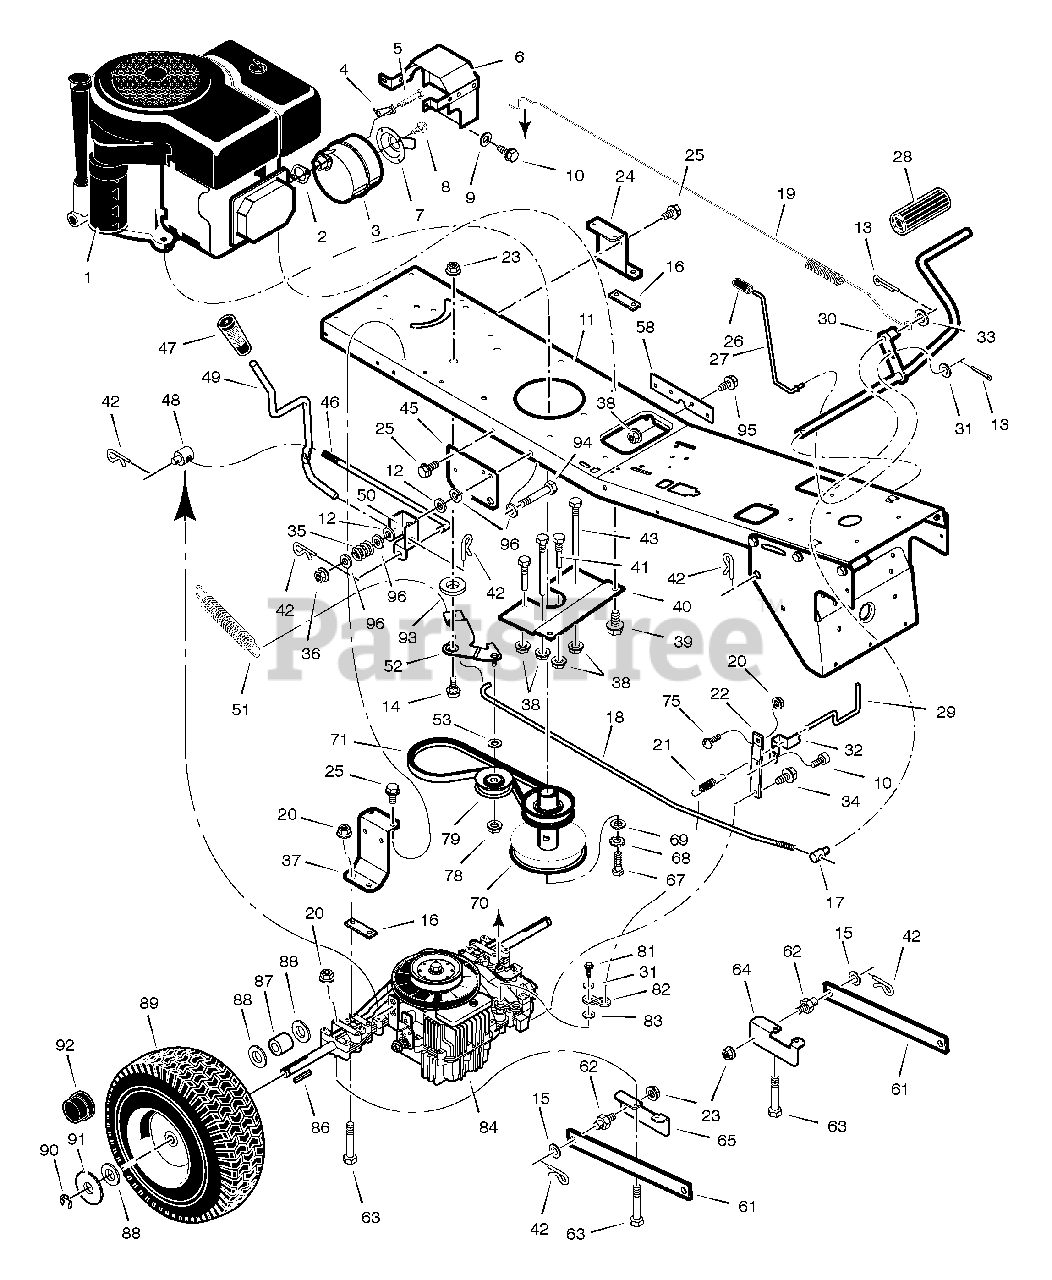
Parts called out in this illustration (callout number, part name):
1	Engine
2	GASKET, Exhaust
3	Muffler
4	Lock, Muffler Screw
5	Bolt, Hex
6	Shield, Heat
7	Tube, Exhaust
9	Washer, Lock
10	Screw
13	Pin, Cotter
14	Bolt, Shoulder
16	Plate, Transaxle
17	Nut, Adjusting
18	Rod, Clutch Hydro
19	Spring, Brake
20	Nut
21	Spring, Roll Release
22	Bracket, Torque Strap
23	Nut
24	Bracket, Left Transaxle
27	Rod, Parking Brake
28	Pedal
29	Rod, Roll Release
30	Rod, Clutch/Brake
32	Bracket, Roll Release
33	Washer
35	Spring, Compression
37	Bracket, Right Transaxle
38	Nut
39	Screw
40	Plate, Belt Guide
41	Guide, Belt -Long
42	Pin, Hair
43	Guide, Belt -Short
45	Bracket, Lift Pivot
46	Rod, Shift Link
47	Grip
48	Nut, Adjusting
49	Lever, Shift
50	Bracket, Pivot
51	Spring - Variator Drive
52	Arm, Idler
58	Plate, Reinforcement
62	Pin, Threaded
63	Bolt, Hex
64	Bracket, Left Rear Hanger
65	Bracket, Right Rear Hanger
67	Bolt, Hex
68	Lockwasher
70	Pulley Stack
71	Belt, Drive
75	Bolt, Carriage
78	Locknut
79	Pulley, Idler
81	Cap Screw
82	Arm, Disconnect
84	Transaxle
86	Key, Square
87	SPACER, Rear Wheel
89	Wheel & Tire Assembly
92	Hub Cap
93	Washer
94	Bolt, Hex
96	Washer
